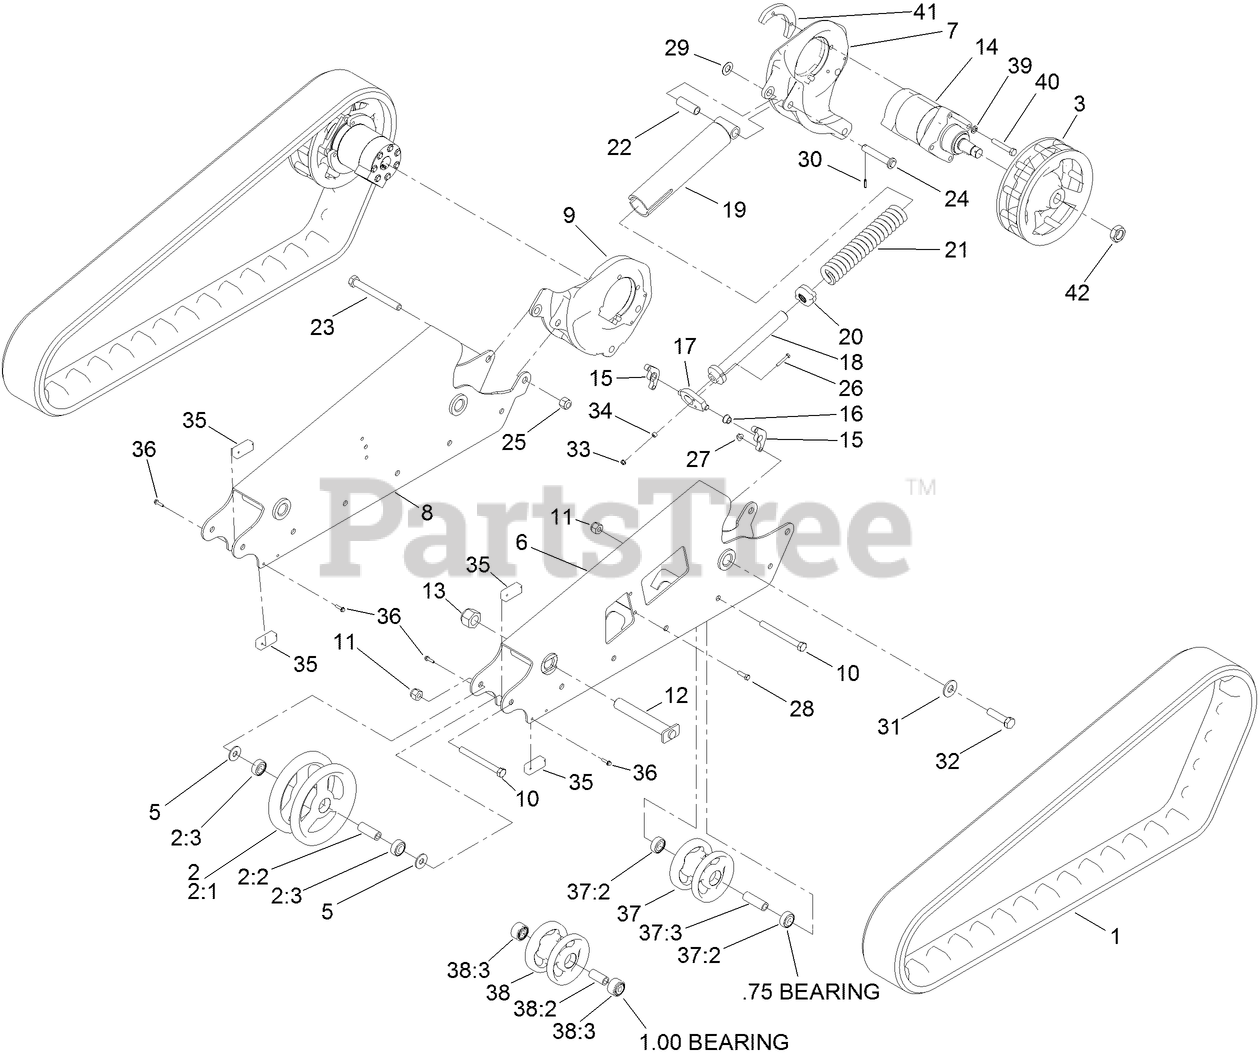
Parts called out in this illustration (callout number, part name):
2	TENSIONER WHEEL ASM
2:1	WHEEL-TENSIONER
2:2	SPACER-WHEEL, TENSIONER
2:3	BEARING-BALL
3	WHEEL-DRIVE
5	WASHER-FLAT
6	MOUNT-NARROW WHEEL, LH
7	MOUNT-WHEEL, LH
8	MOUNT-NARROW WHEEL, RH
9	MOUNT-WHEEL, RH
10	SCREW-HH
11	NUT-HEX
12	PIN-TRACK
13	NUT-HH
14	MOTOR-HYD
15	PLATE-MOUNT, PIVOT
16	BUSHING-BELLCRANK
17	TENSIONER-PIVOT JOINT
18	BOLT-TENSIONER
19	PIVOT-TENSIONER
20	BLOCK-TENSIONER
21	SPRING-COMPRESSION
22	SPACER-PIVOT
23	SCREW-HH
24	PIN-TENSIONER
25	NUT-LOCK
26	SCREW-HH
27	NUT-HF, NI
28	SCREW-HH
29	WASHER-FLAT
30	PIN-SPRING
31	WASHER
32	SCREW-HH
33	NUT-HHF
34	SPACER
35	BLOCK-TRACK
36	SCREW-HHF
37	WHEEL ASM
37:2	BEARING-BALL
37:3	SPACER-WHEEL
38	WHEEL ASM
38:2	SPACER-WHEEL, ROAD
38:3	BEARING-BALL
39	WASHER-LOCK
40	SCREW-HH, TAP
41	PLATE-MOUNTING
42	NUT-HEX
